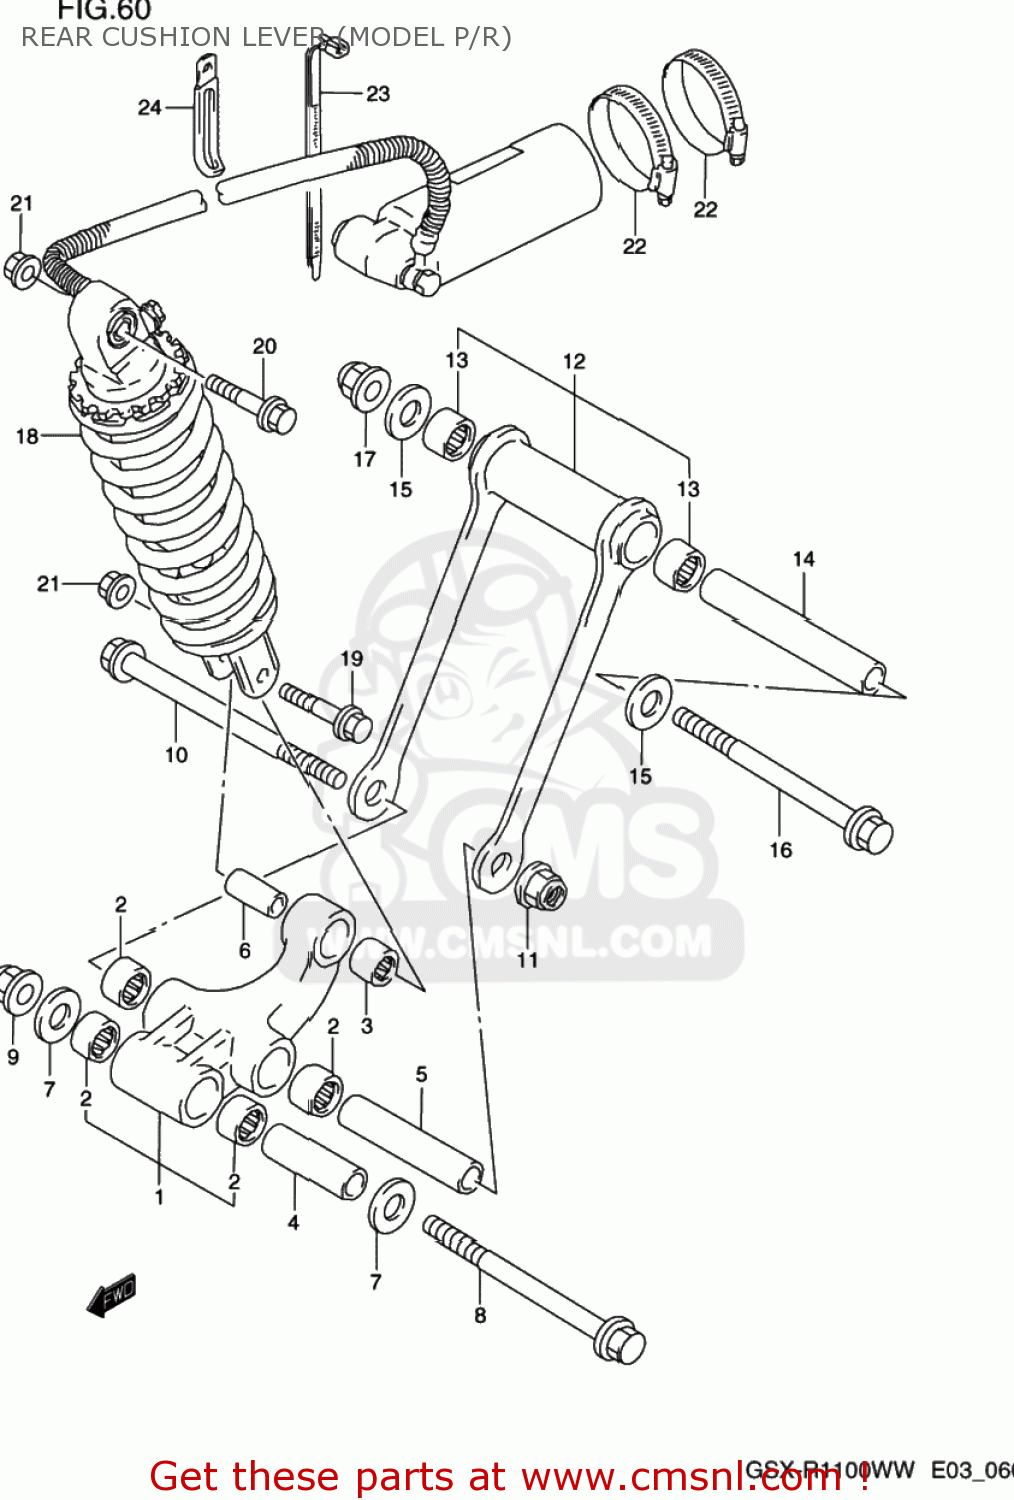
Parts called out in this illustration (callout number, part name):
1	LEVER SET,REAR CUSHION
2	BEARING(20X27X23.5)
3	BEARING(17X24X26)
4	SPACER,RR CUSHION LEVER
5	SPACER,RR CUSHION ROD
6	SPACER,RR CUSHION LEVER
7	WASHER
8	SHAFT,RR CUSHION LEVER FR
9	NUT
10	SHAFT,RR CUSHION ROD
11	NUT
12	ROD SET,RR CUSHION LEVER
13	BEARING(20X27X23.5)
14	SPACER (14X20X122)
15	WASHER
16	BOLT(14X161)
17	NUT
18	ABSORBER ASSY,RR SHOCK
19	BOLT(10X58)
20	BOLT(10X54)
21	NUT
22	CLAMP
23	CLAMP(L:165)
24	CLAMP
